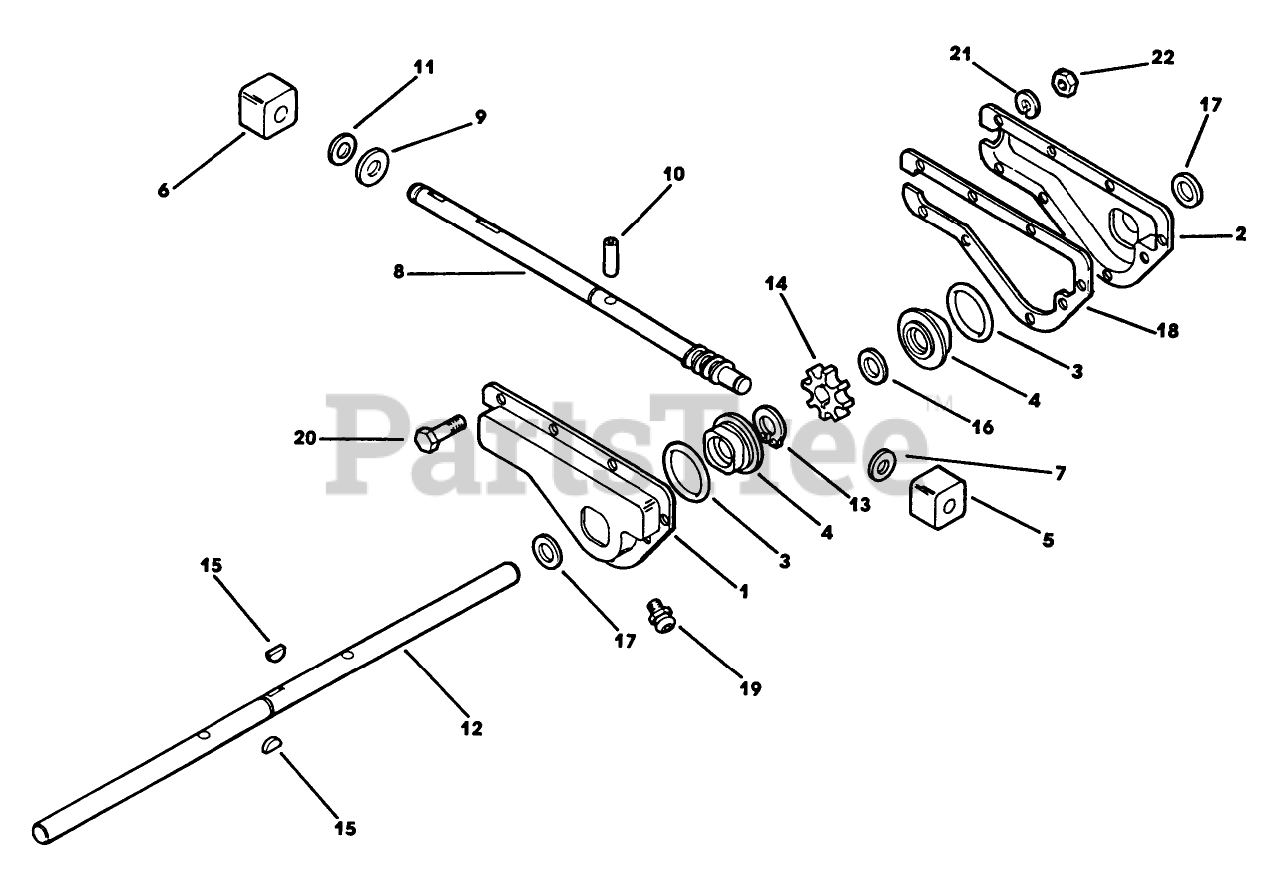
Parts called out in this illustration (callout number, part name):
1	GEARCASE HALF RH *B
3	O-RING
4	BEARING
5	BEARING
6	BEARING
7	WASHER - SHIM
9	WASHER
12	SHAFT - AUGER
13	RING-RETAINING
14	WORM WHEEL S
16	WASHER
17	SEAL
18	GASKET
19	FITTING-GREASE
20	SCREW
22	NUT
